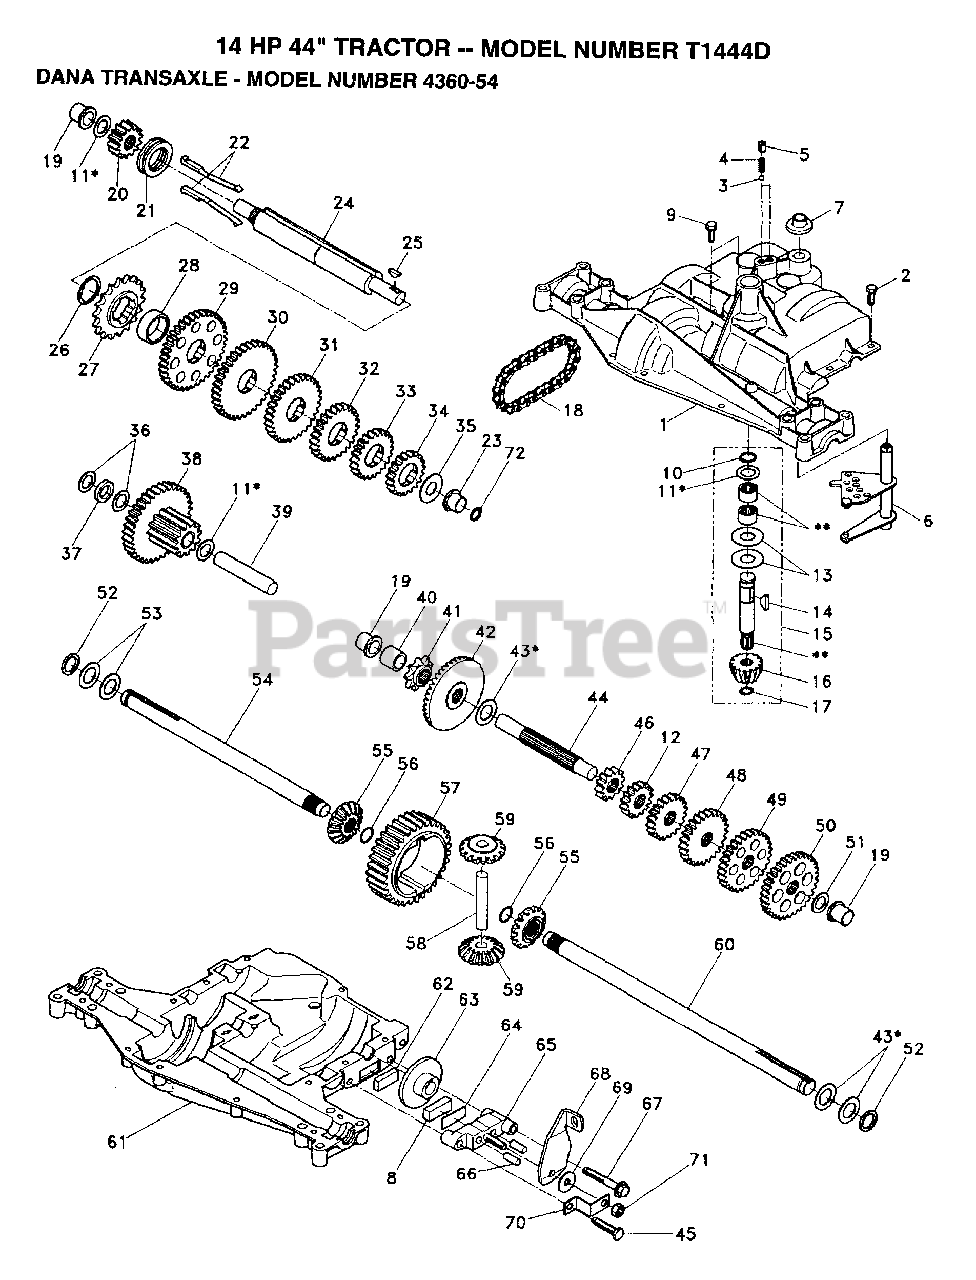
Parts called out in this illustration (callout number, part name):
4	"SPRING, DETENT LT"
5	"SCREW, SET LT"
6	SHIFTER.ASM.KIT.
7	SHIFTER BOOT
8	PUCK T
9	SCREW TAP W/SEAL
10	RETAINING RING LT
11	ASM KIT SHIM 4689
13	WASHER T
14	WOODRUFF KEY
17	"RING,RETAINING LT"
18	"CHAIN,24 PTCH LT"
19	BEARING.FLNG.5510
20	GEAR SPUR 14T
21	COLLAR CLUTCH
22	KIT.ASM.CLUTCH KY
23	"FLANGE, BEARING"
24	SHAFT INTERM
25	WOODRUFF KEY
26	"RING,RETAINING LT"
27	SPROCKET 18T T
28	SPACER YT
29	KIT.GEAR.12/37TH
31	GEAR SPUR 30T
32	GEAR 25T LT
33	GEAR SPUR 22 TT
34	SPUR GEAR 19T
35	"WASHER, PLAIN LT"
36	WASHER 025
37	SPACER
38	ASSM GEAR COMB
39	SHAFT IDLER
40	SPACER T
41	SPROCKET 9T LT
43	ASM KIT SHIM
44	SHAFT T
45	"SCREW, TAPPING LT"
48	"GEAR, SPUR 25T LT"
49	GEAR 28T T
50	"GEAR, SPUR 31T LT"
51	WASHER 060
52	NEOPRENE WASHER
53	WASHER 031
55	GEAR LT
56	"RING,RETAINING LT"
58	SHAFT T
59	"GEAR,MITER 15T YT"
62	PUCK T
63	BRAKE DISC. T
64	SPACER LT
66	PIN T
69	WASHER LT
71	NUT.LOCK.5/16-24
72	SQUARE RING
